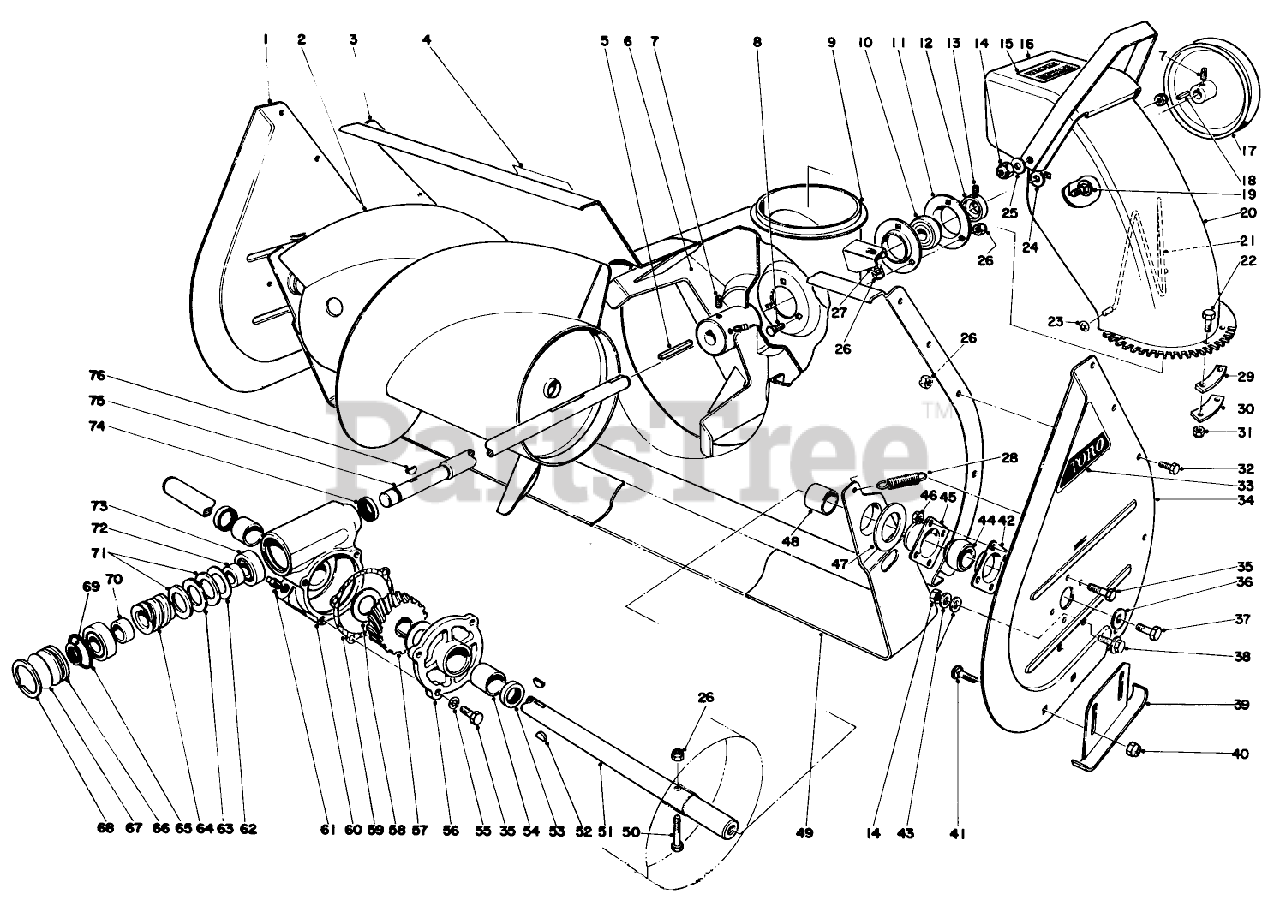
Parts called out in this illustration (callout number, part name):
1	Side Plate
2	Auger R.H.
3	Auger Housing (Incl. Ref. #4)
4	Decal
6	IMPELLER ASM
7	SCREW-SET, SQH
8	BOLT-CARR
9	SUPPORT B
10	BALL BRG W/COLLAR
11	BRG FLANGE
12	EXT LOCKING COLLAR
13	SCREW-HSH
14	NUT-LOCK, CONE
15	CHUTE WARNING DECAL
16	Deflector (Incl . Ref. #15)
17	1/2 X 9.5 DIA PULLEY
18	SQUARE KEY
19	SCREW-CARR
20	Upper Chute
21	WIRE-CHUTE
22	SCREW-HWH
23	NUT-PUSH
24	WASHER-RUBBER
25	WASHER-BELLEVILLE
26	NUT-LOCK, CONE
27	WASHER-LOCK
28	SPRING-TENSION
29	UPPER CHUTE TAB
30	CHUTE TAB SPACER
31	Nut
32	SCREW-HH
33	AUGER SIDE PLT DECAL
34	Side Plate L. H.
35	SCREW-HH
36	WASHER
37	SCREW-HH
38	SCREW-HHF
39	Skid
40	NUT-HHF, WHIZ
41	SCREW-CARR
42	BEARING-FLANGE, REAR
43	WASHER-FLAT
44	BEARING
45	BEARING-FLANGE, FRONT
46	NUT-LOCK, CONE
47	SCRAPER BLADE SPACER
48	SPACER
49	SCRAPER BLADE 32" R
50	Auger Bolt
51	Auger Shaft
52	KEY-WOODRUFF
53	SEAL-OIL
54	BUSHING
55	WASHER-LOCK
56	Gear Box Cover(Incl.Ref. #53&54)
57	GEAR-WORM, 27T
58	WASHER-THRUST
59	Gasket
60	Gear Box(Incl.Ref. #53-54&72)
61	PLUG-PIPE, SQH
62	Thrust Race
63	Thrust Bearing
65	O-RING
68	INTRNL RETAINING RING
69	Ring-Snap
70	Spacer
71	Thrust Race
72	Spacer
73	.750 BALL BEARING
74	SEAL-OIL
75	WORM SHAFT
76	KEY-WOODRUFF
